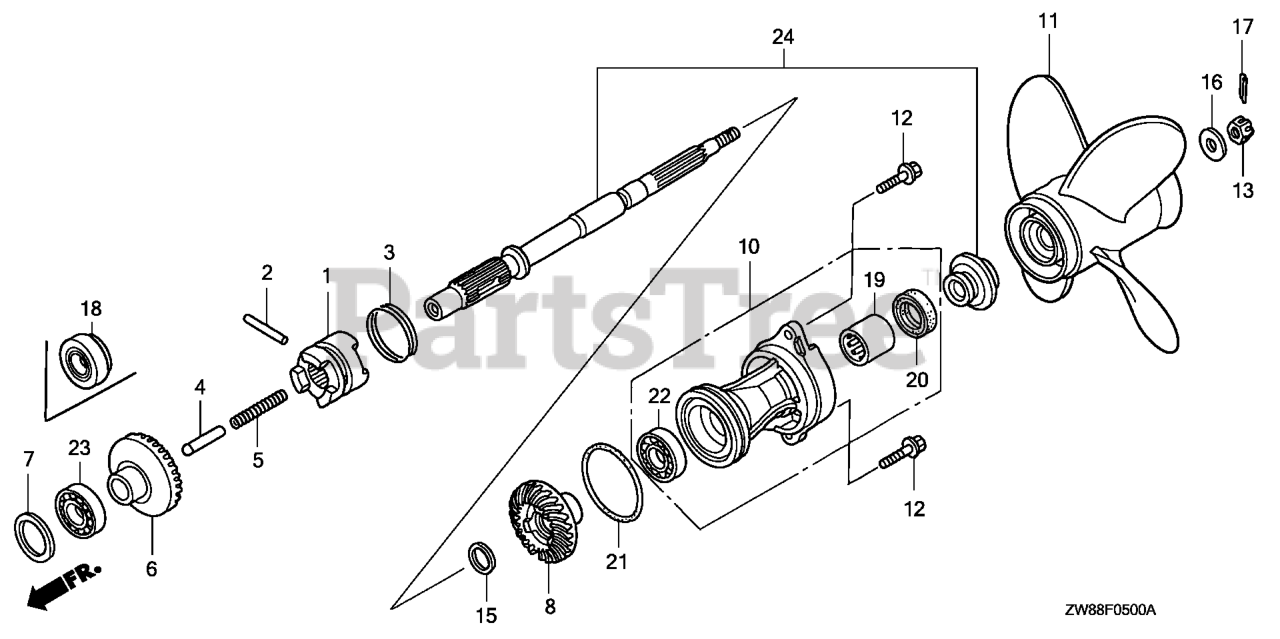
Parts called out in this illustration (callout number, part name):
1	SHIFTER, CLUTCH
2	PIN, SHIFTER (4X30)
3	RING, CROSS PIN
4	SLIDER, SHIFT
5	SPRING, SHIFT
6	GEAR, FR. BEVEL
7	SHIM A (40MM)
7	SHIM B (40MM)
7	SHIM C (40MM)
8	GEAR, RR. BEVEL
9	SHAFT KIT, PROPELLER
10	HOLDER ASSY., PROPELLER SHAFT *NH282MU* (OYSTER SILVER METALLIC-U)
11	PROPELLER, FOUR BLADES (10X6-1/2 HT) *NH283* (STIN GRAY)
11	PROPELLER, FOUR BLADES (9-1/4X7) *NH283*
11	PROPELLER, FOUR BLADES (9-1/4X10) *NH283*
11	PROPELLER, FOUR BLADES (9-1/4X11) *NH283*
11	PROPELLER, FOUR BLADES (9-1/4X8) *NH283* (STIN GRAY)
11	PROPELLER, FOUR BLADES (9-1/4X9) *NH283* (STIN GRAY)
12	BOLT, FLANGE (6X20) (ENGINE NO.)
13	NUT, CASTLE (10MM)
14	WASHER, PROPELLER THRUST
15	WASHER (18MM)
16	WASHER (10MM)
17	PIN, COTTER (3MM)
19	BEARING, NEEDLE (17X24X20) (NTN)
20	SEAL, WATER (17MM)
21	O-RING (59.4X3.1)
22	BEARING, RADIAL BALL (6005)
23	BEARING, RADIAL BALL (6005)
24	SHAFT KIT, PROPELLER
